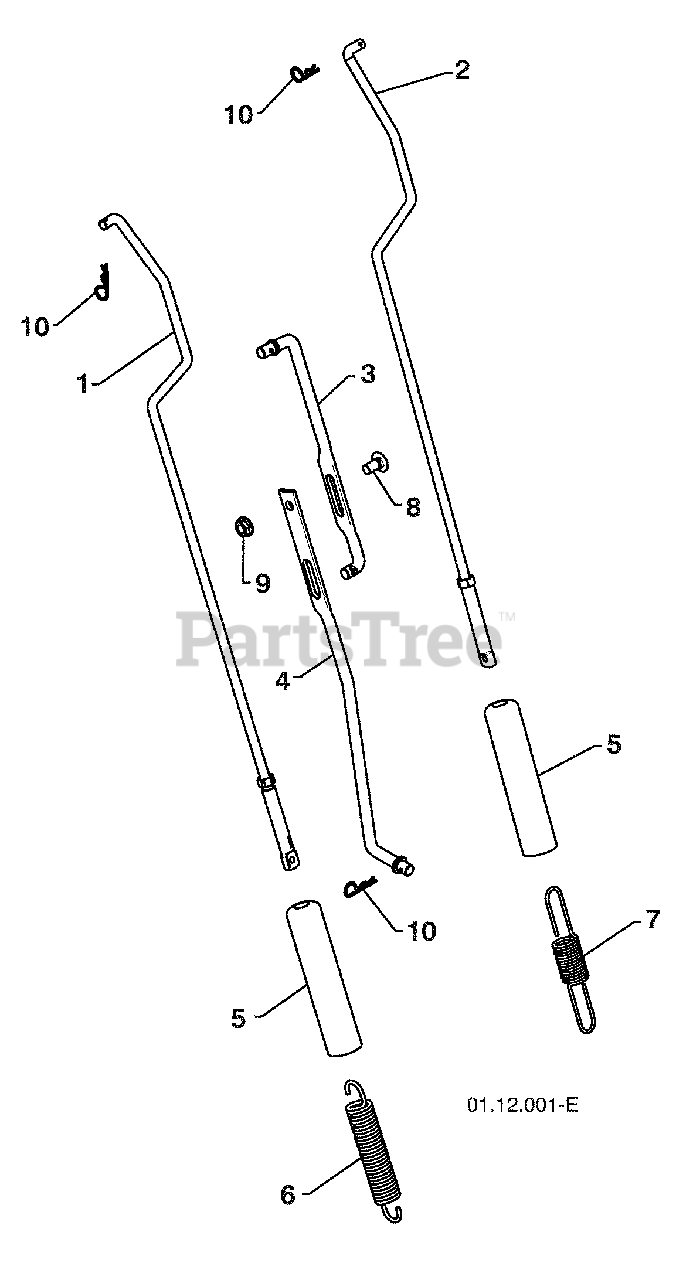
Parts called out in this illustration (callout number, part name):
1	IMPELLER ROD ASSEMBLY
2	TRACTION ROD ASSEMBLY
3	SHIFTER ROD TOP
4	SHIFTER ROD BOTTOM
5	SPRING SLEEVE
6	IMPELLER SPRING
7	TRACTION SPRING
8	CARRIAGE BOLT 5/16-18 X .75
9	NUT 5/16-18
